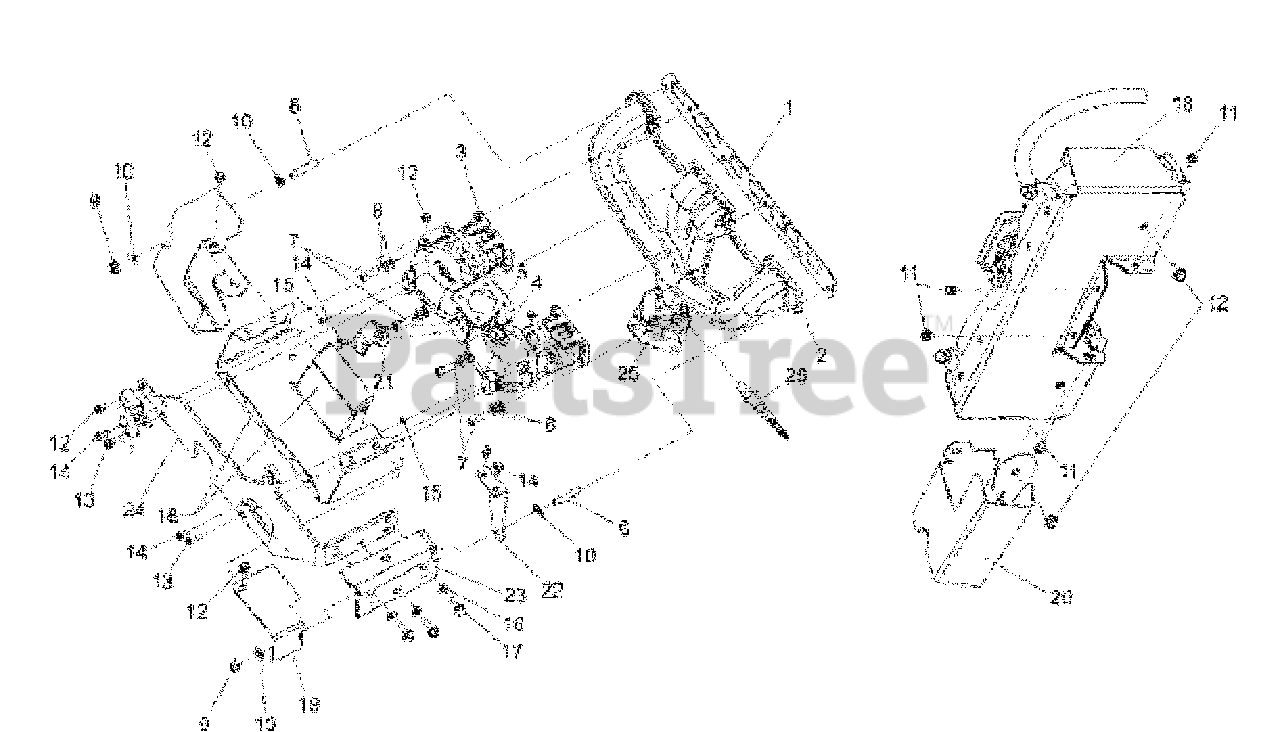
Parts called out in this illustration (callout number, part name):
1	GASKET
2	MANIFOLD, Exhaust
3	INTAKE, Manifold
4	FITTING
5	FITTING
6	STUD
7	BOLT
8	WASHER
9	NUT
10	WASHER
11	SCREW
12	SCREW
13	SCREW
14	SCREW
15	WASHER
16	WASHER
17	SCREW
18	HEATSHIELD
19	HEATSHIELD
20	HEATSHIELD
22	BRACKET
23	BRACKET
24	BRACKET
